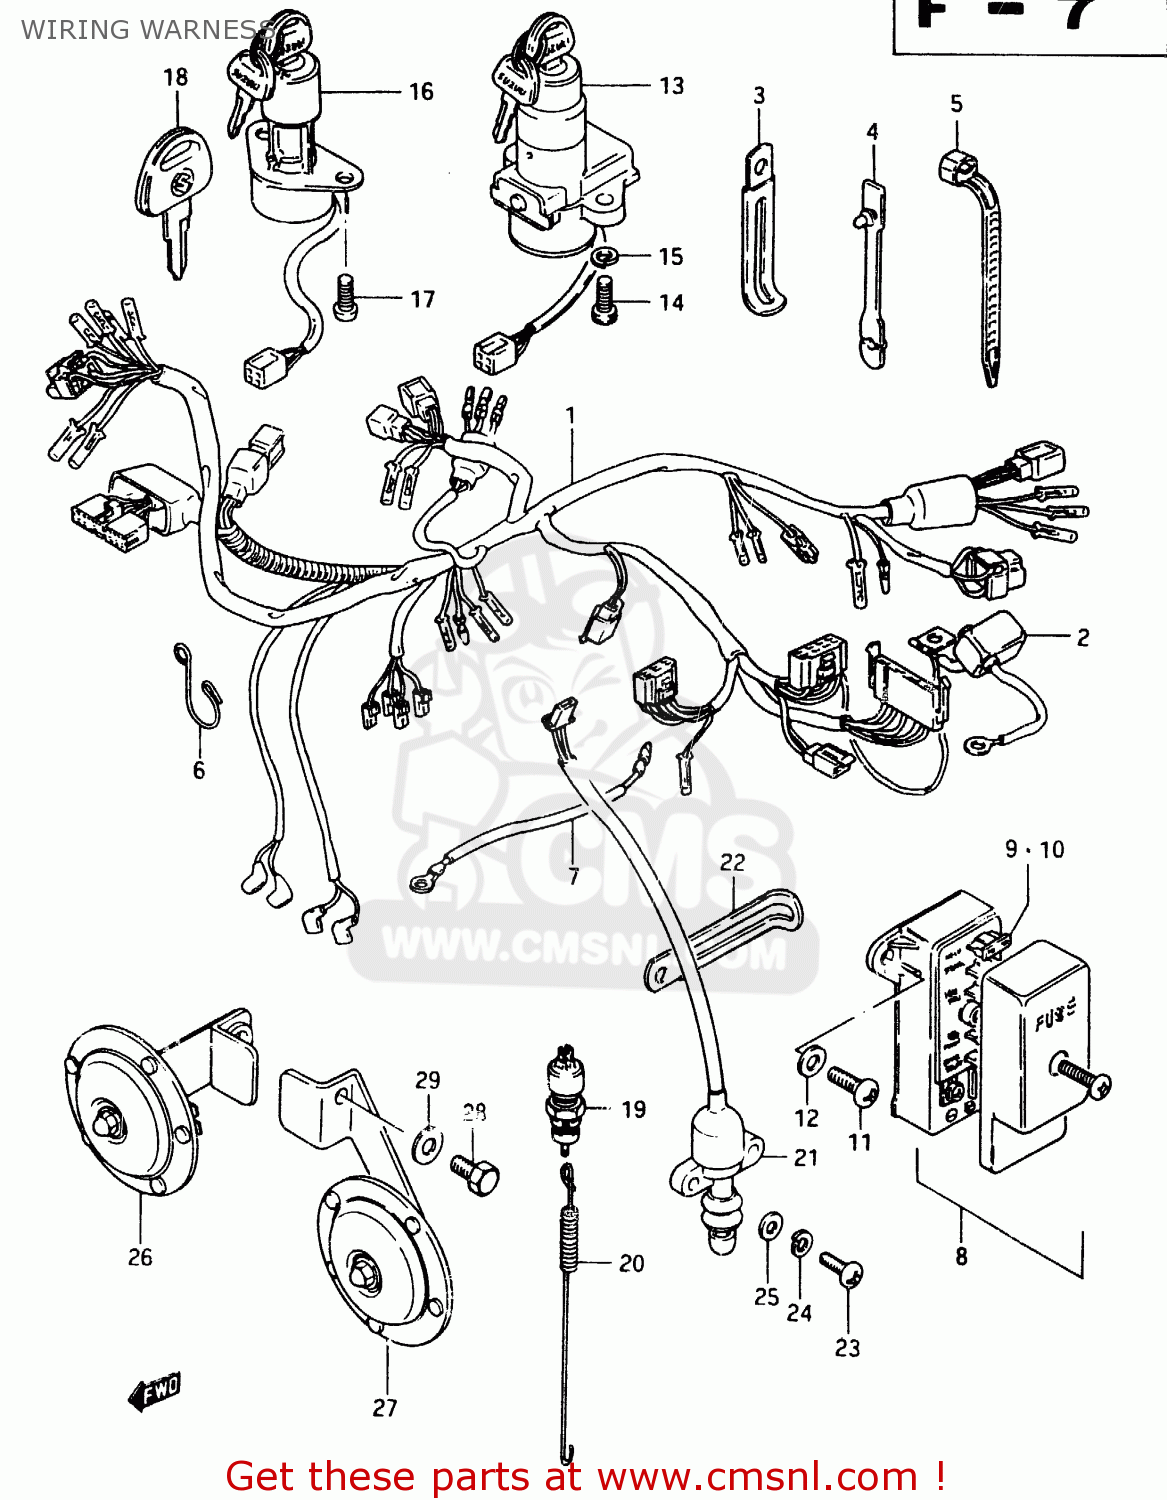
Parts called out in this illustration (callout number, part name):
1	HARNESS,WIRING
2	CAP,BATTERY PLUS TERMINAL
3	CLAMP
4	CLAMP,L:88
5	CLAMP(L:95)
6	CLIP,WIRING HARNESS
7	WIRE
8	BOX ASSEMBLY,FUSE
9	FUSE(10A)
10	FUSE(15A)
11	SCREW
12	WASHER, LOWER
13	SWITCH ASSY,IGNITION
14	BOLT
15	WASHER,LOCK
16	IGN SWITCH/STE
17	SCREW 6X12
18	KEY,BLANK
19	SWITCH ASSEMBLY,STOP LAMP
20	SPRING
21	SWITCH ASSEMBLY,SIDE STAND
22	CLAMP
23	SCREW 5X20
24	WASHER,LOCK
25	WASHER,5MM
26	HORN, HIGH PITCHED
27	HORN, LOW PITCHED
28	BOLT
29	WASHER
